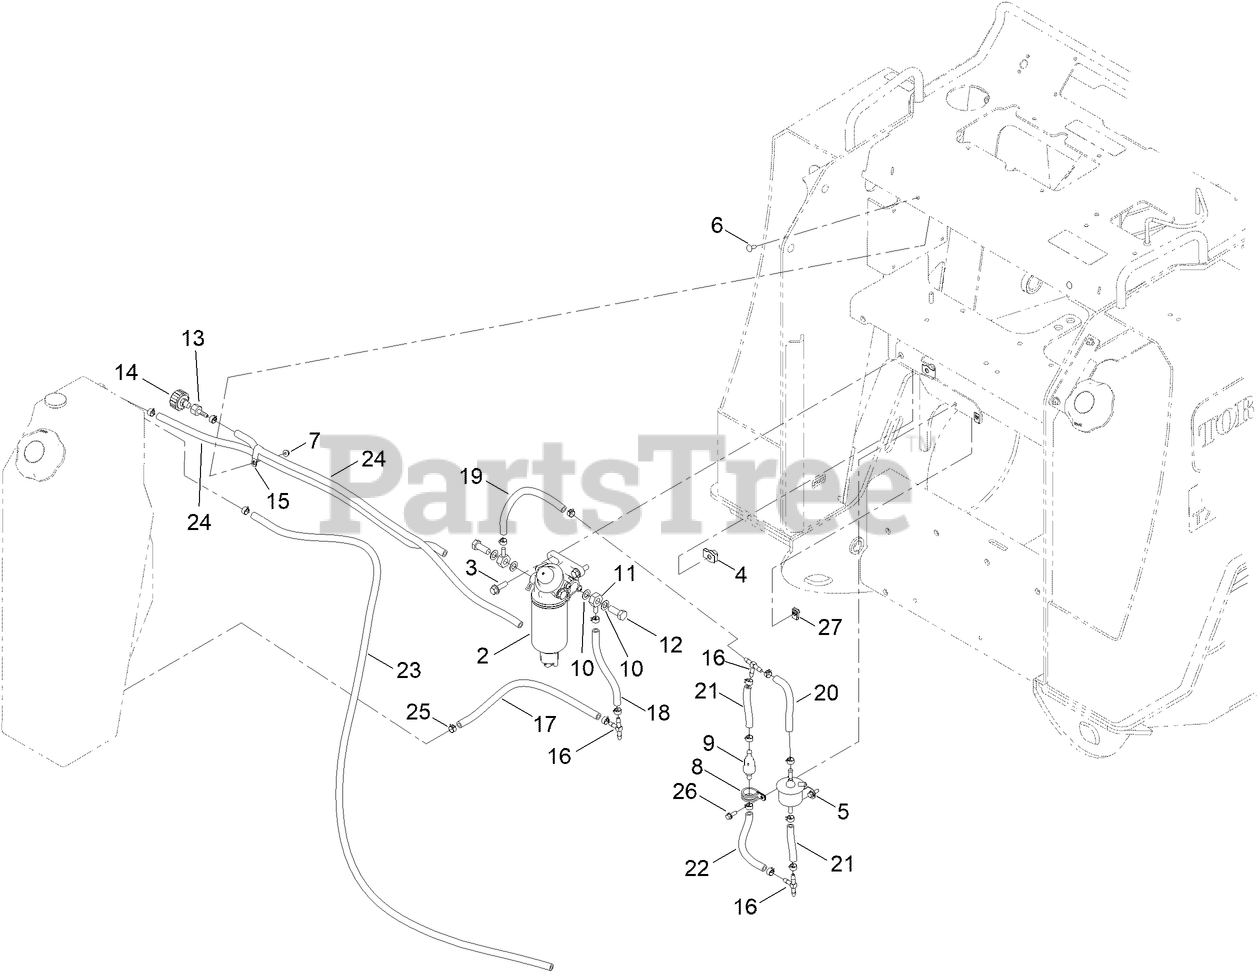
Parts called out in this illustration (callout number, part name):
2	FILTER-SEPERATOR, WATER
3	SCREW-HHF
4	NUT-TINNERMAN
5	ASSY PUMP,FUEL
6	BOLT-CARR
7	NUT-HF
8	R-CLAMP
9	VALVE-BYPASS
10	O-RING
11	ADAPTER-FUEL
12	SCREW-ADAPTER
13	FITTING-STRAIGHT
14	BREATHER
15	CLAMP-R, DOUBLE TUBE
16	FITTING-TEE, BARBED
17	HOSE-FUEL
18	HOSE-FUEL
19	HOSE-FUEL
20	HOSE-FUEL
21	HOSE-FUEL
22	HOSE-FUEL
23	HOSE-FUEL
24	HOSE-FUEL
25	CLAMP-HOSE
26	SCREW-HHF
